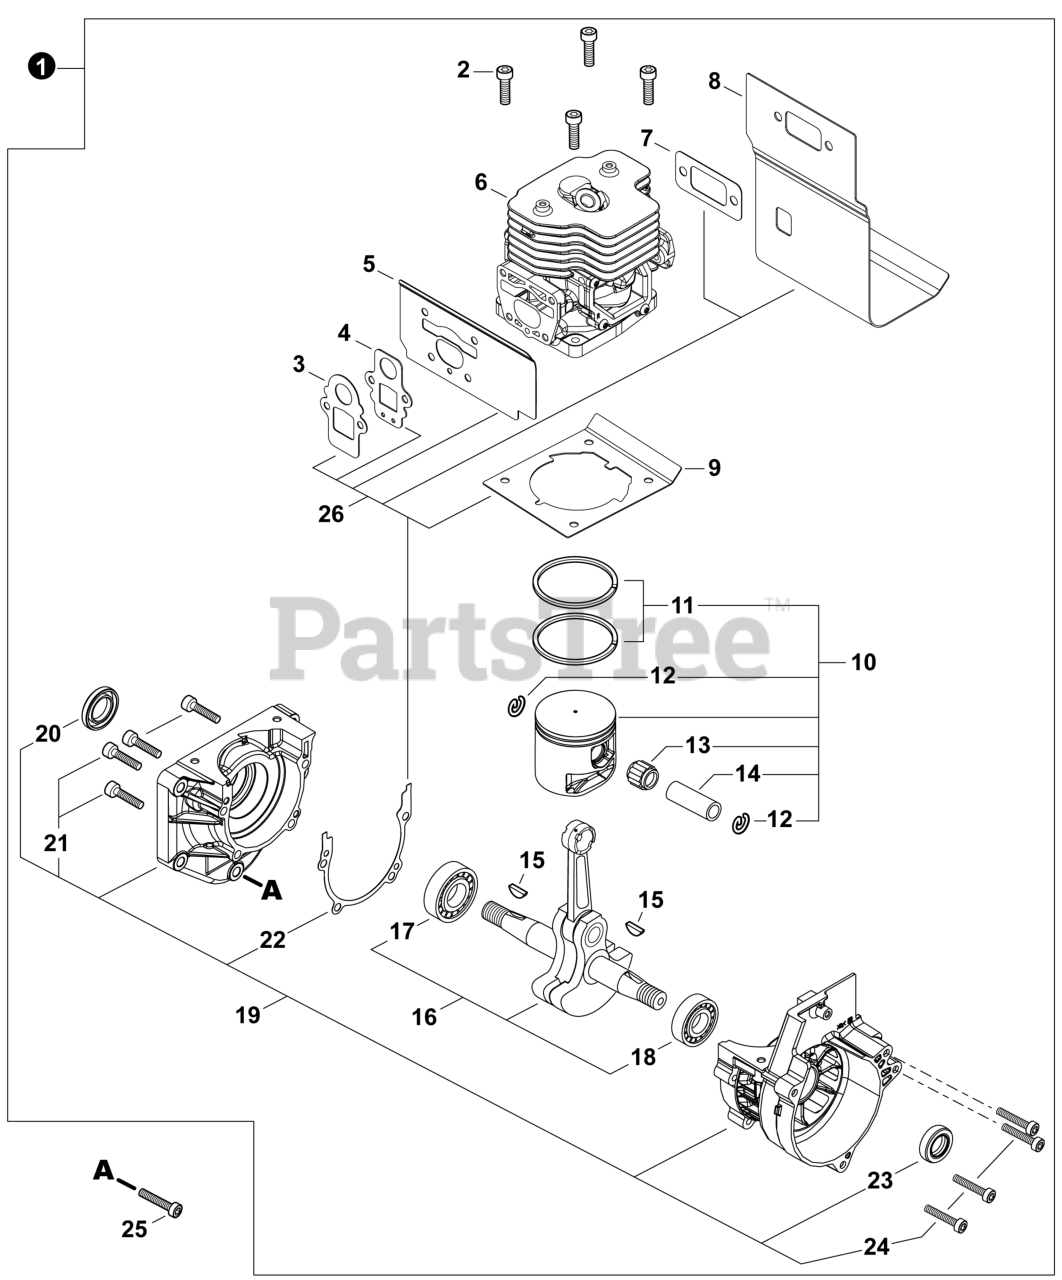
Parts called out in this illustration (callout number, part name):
1	SHORT BLOCK
2	BOLT, TORX 5x25
3	GASKET, INTAKE
4	GASKET, INTAKE
5	HEAT SHIELD, INTAKE
6	CYLINDER ASSY
7	GASKET, EXHAUST
8	HEAT SHIELD, EXHAUST
9	GASKET, CYLINDER
10	PISTON KIT
11	RING, PISTON
12	RING, RETAINING
13	BEARING, NEEDLE 13
14	PIN, PISTON
15	KEY, WOODRUFF 3x14
16	CRANKSHAFT ASSY
17	BEARING, BALL 6203
18	BEARING, BALL 6202
19	CRANKCASE SET
20	SEAL, OIL 17
21	BOLT, TORX 5x35
22	GASKET, CRANKCASE
23	SEAL, OIL 15
24	BOLT 5x20
25	BOLT, TORX 6x30
26	GASKET KIT: ENGINE, INTAKE, EXHAUST
